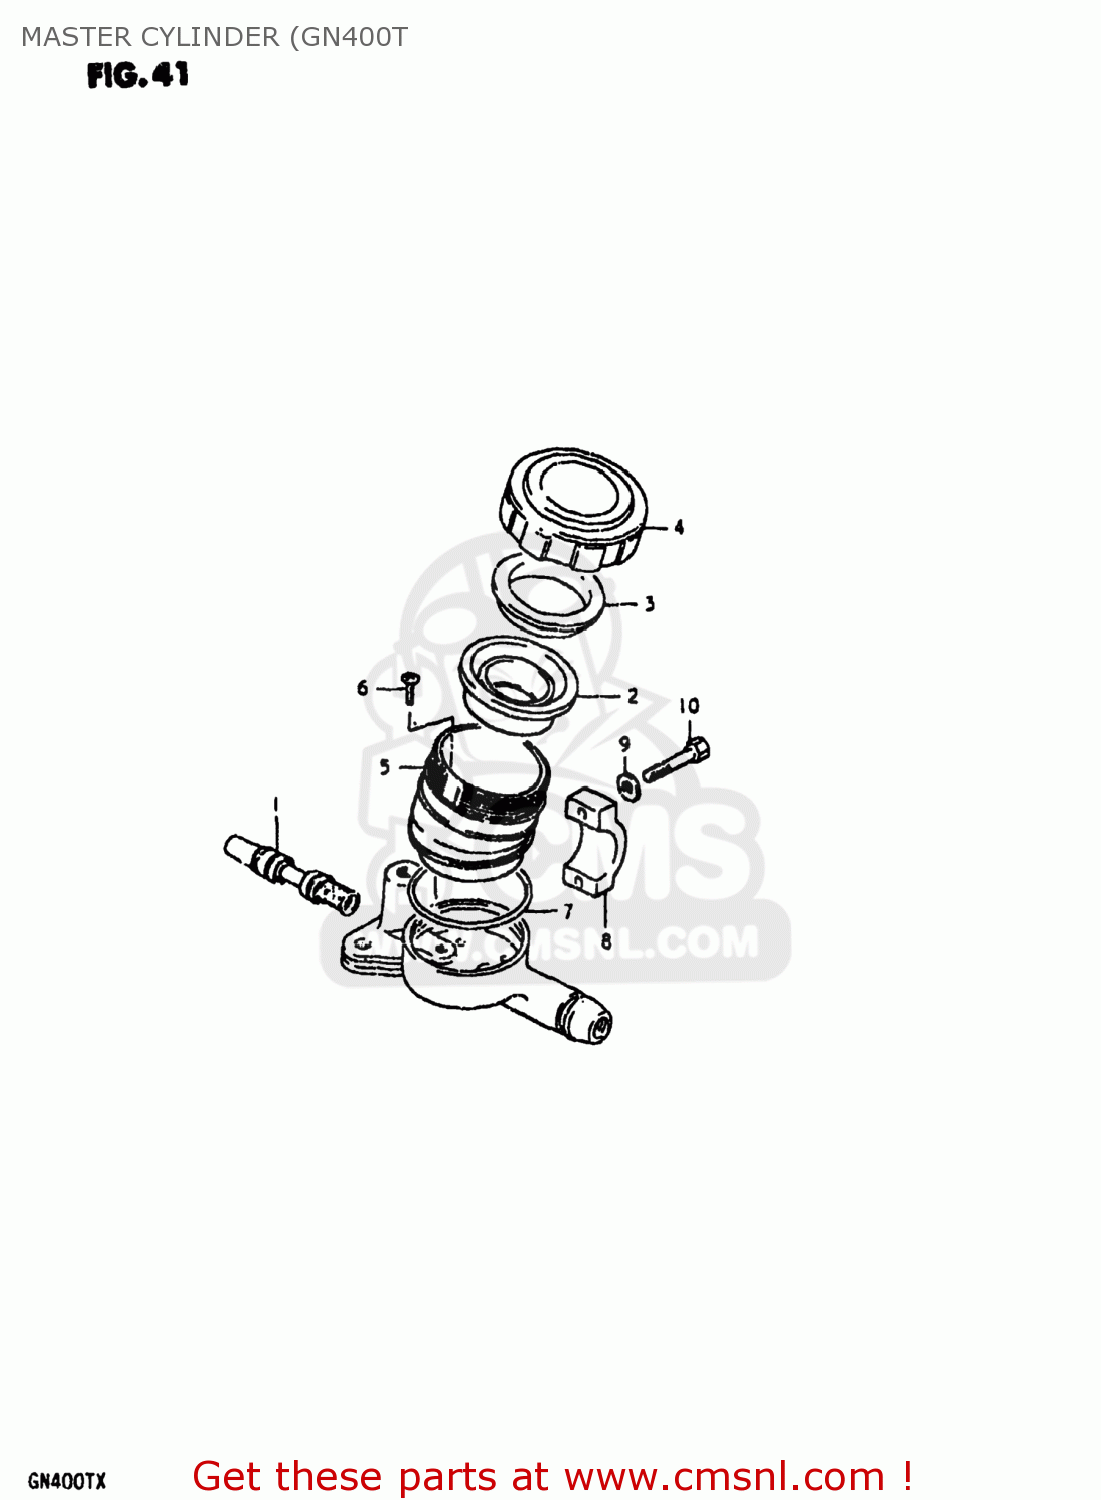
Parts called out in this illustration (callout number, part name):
1	CUP SET,MASTER CYLINDER
2	DIAPHRAGM
3	PLATE,DIAPHRAGM
4	CAP
5	RESERVOIR
6	SCREW,MASTER CYLINDER
7	O RING
8	HOLDER,MASTER CYLINDER
9	WASHER
10	BOLT
